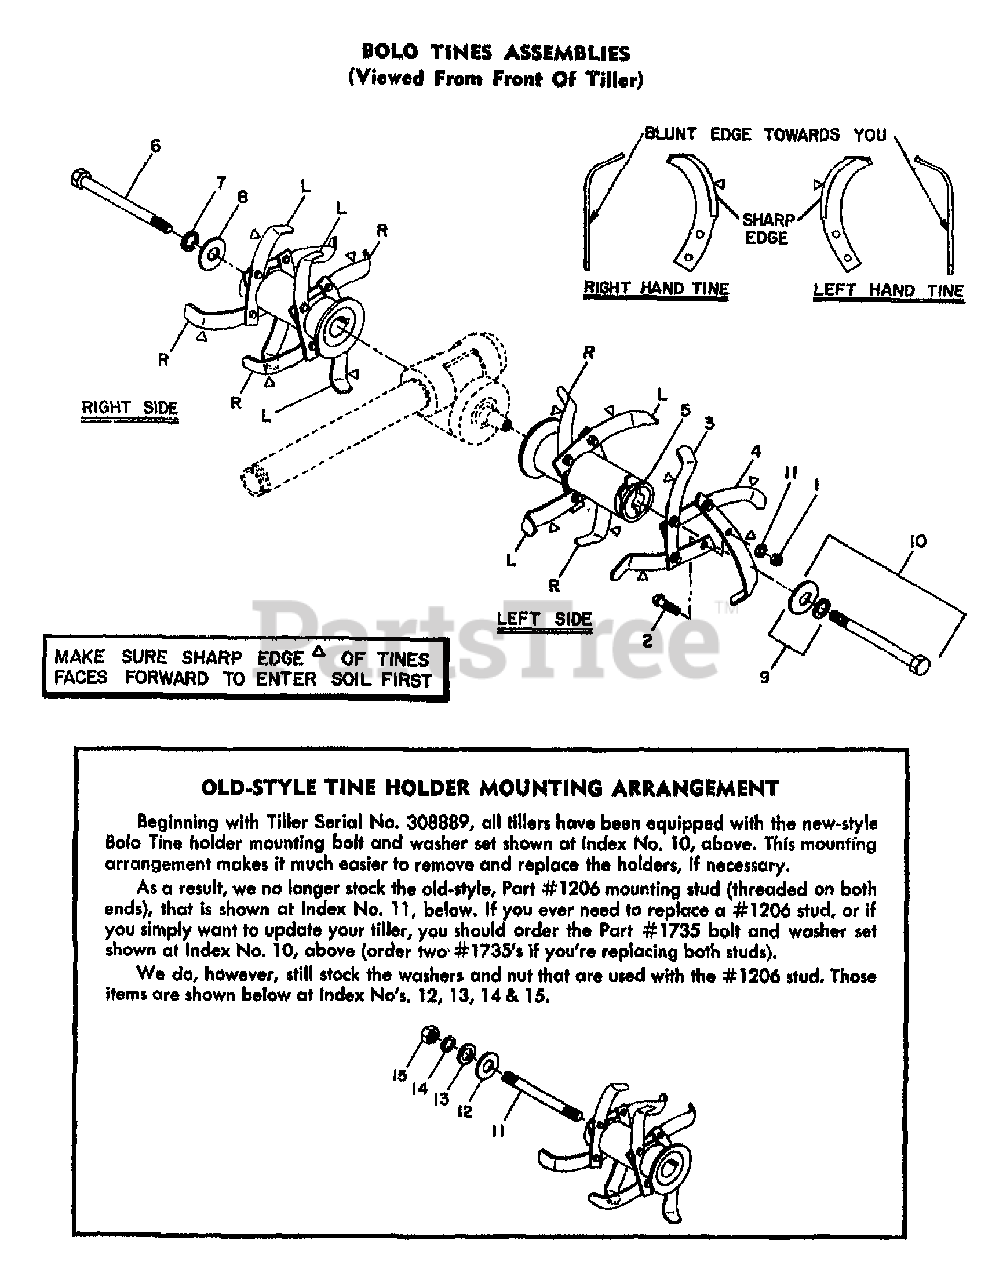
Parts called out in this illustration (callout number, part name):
1	NUT-HEX 3/8-16 ZP
2	SCR-HH 3/8-16X1.0 G5 ZP
3	TINE-BOLO RT W/HDW
4	TINE-BOLO LT W/HDW
5	HOLDER-TINE W/SHIELD
6	BOLT-HH 1/2-20 X 5.75 ZP
7	WASHER-LK .5
8	WASHER-#1.75X.531X.187 ZP
9	WASHER-SET BOLO
10	KIT-TINE BOLT & WASHER
11	WASHER-LK .375 @ DEPL
11	KIT-TINE BOLT & WASHER
12	WASHER-1.75X.625X.11
13	WASHER-PLAIN 1/2 ZP
14	WASHER-LK .5
15	NUT-HEX 1/2-20
